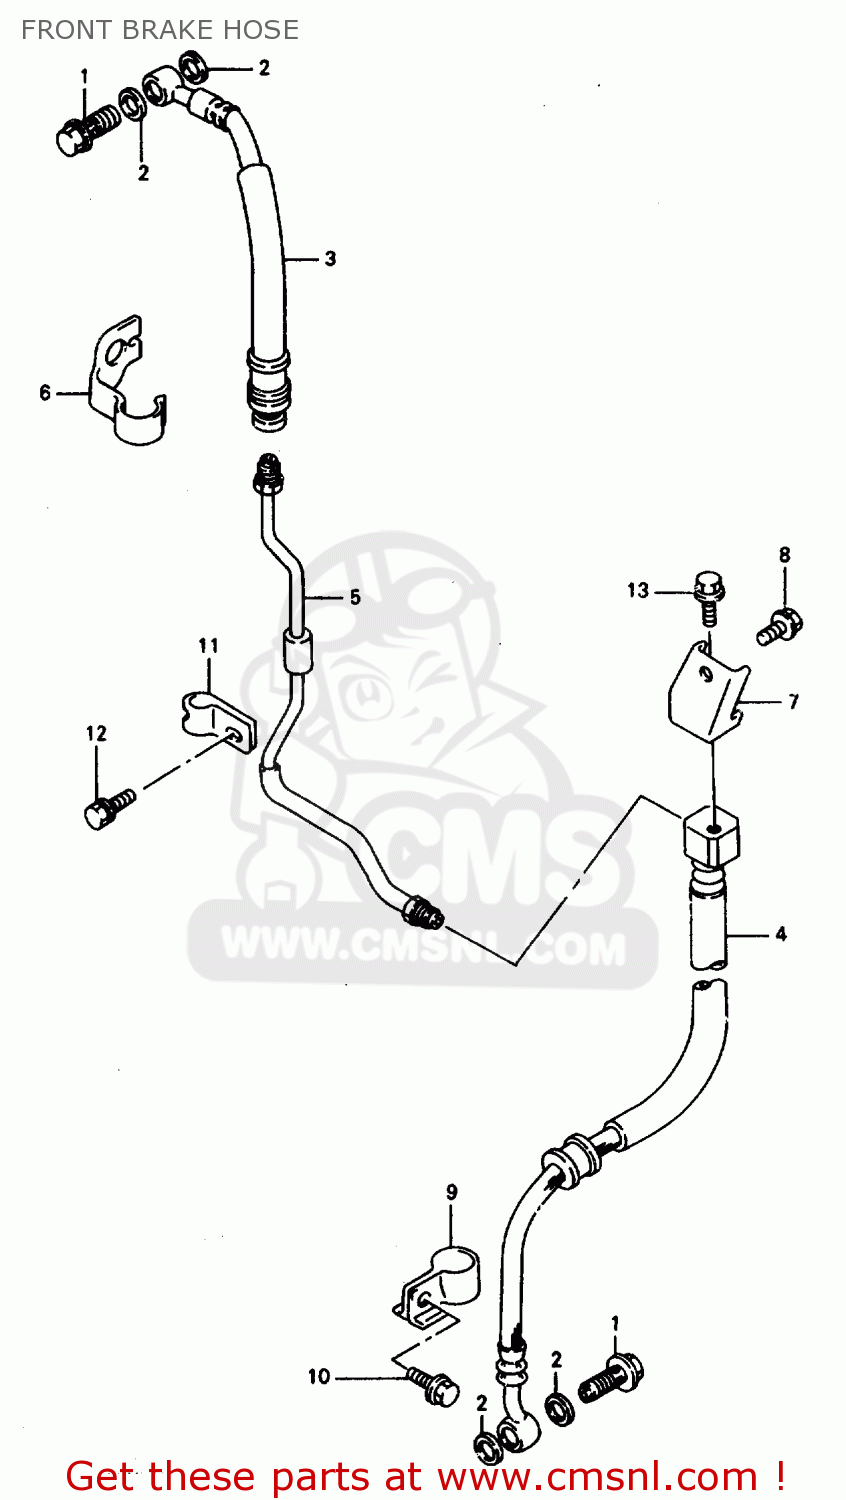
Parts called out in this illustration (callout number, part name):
1	BOLT UNION
2	WASHER(10X15X1.5)
3	HOSE,FR BRAKE NO.1
4	HOSE,FR BRAKE NO.2
5	PIPE,FR BRAKE
6	CLAMP,FR BRAKE HOSE NO.1
7	BRACKET,FR BRAKE HOSE NO.2
8	BOLT
9	CLAMP,FR BRAKE HOSE NO.2
10	BOLT
11	CLAMP
12	BOLT
13	BOLT
